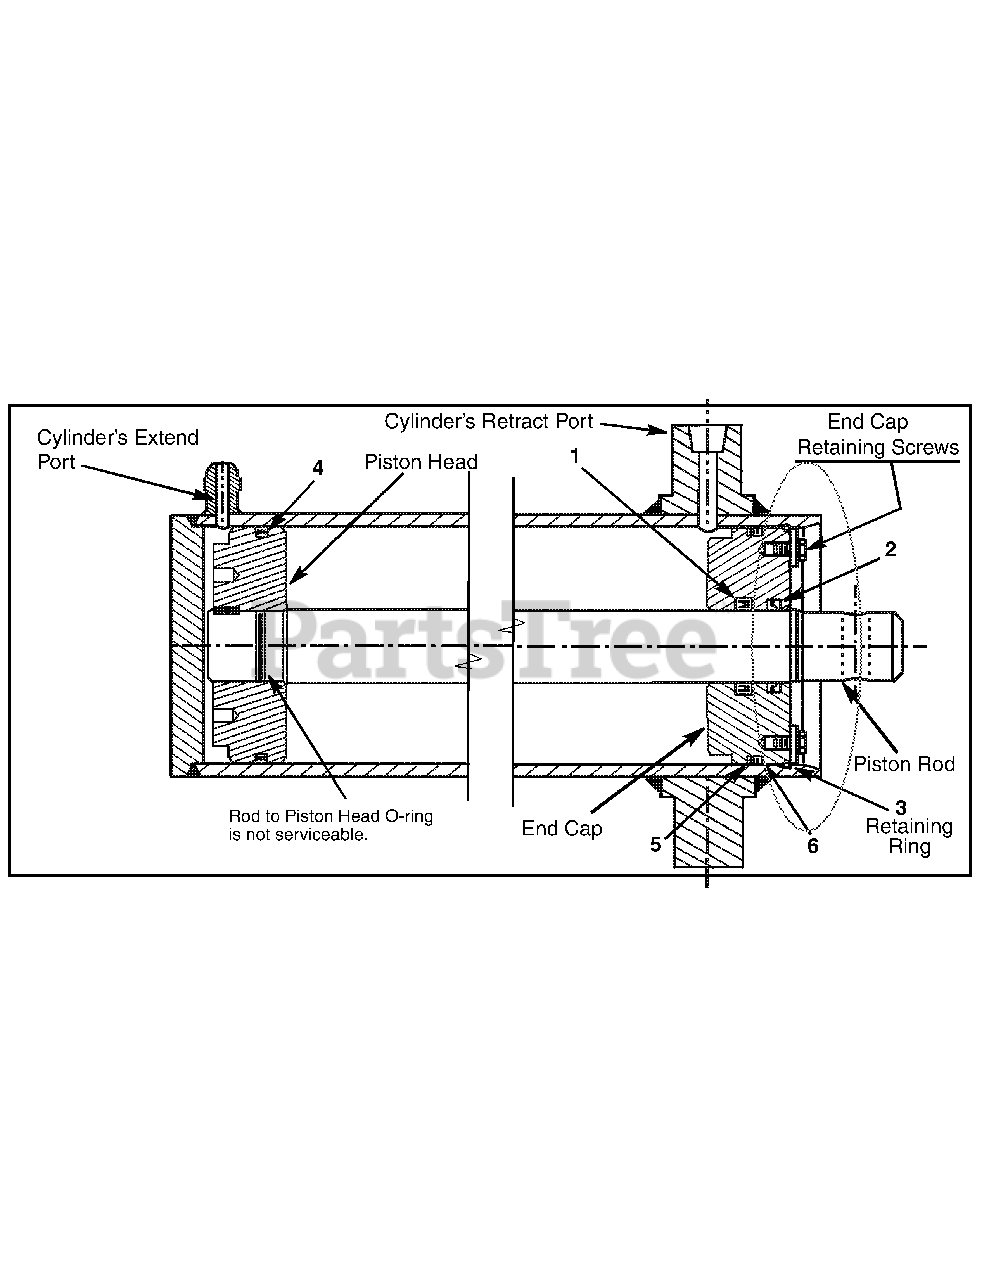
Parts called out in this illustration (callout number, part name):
1	Zurcon U-Cup RU3 (Blue)
2	Scraper DA17 (Black)
3	Retaining-Ring (Metal)
4	Zurcon Wynseal (Blue)
5	O-Ring (Black)
6	Back-up Ring (White)
7	INSTRUCTION SHEET
